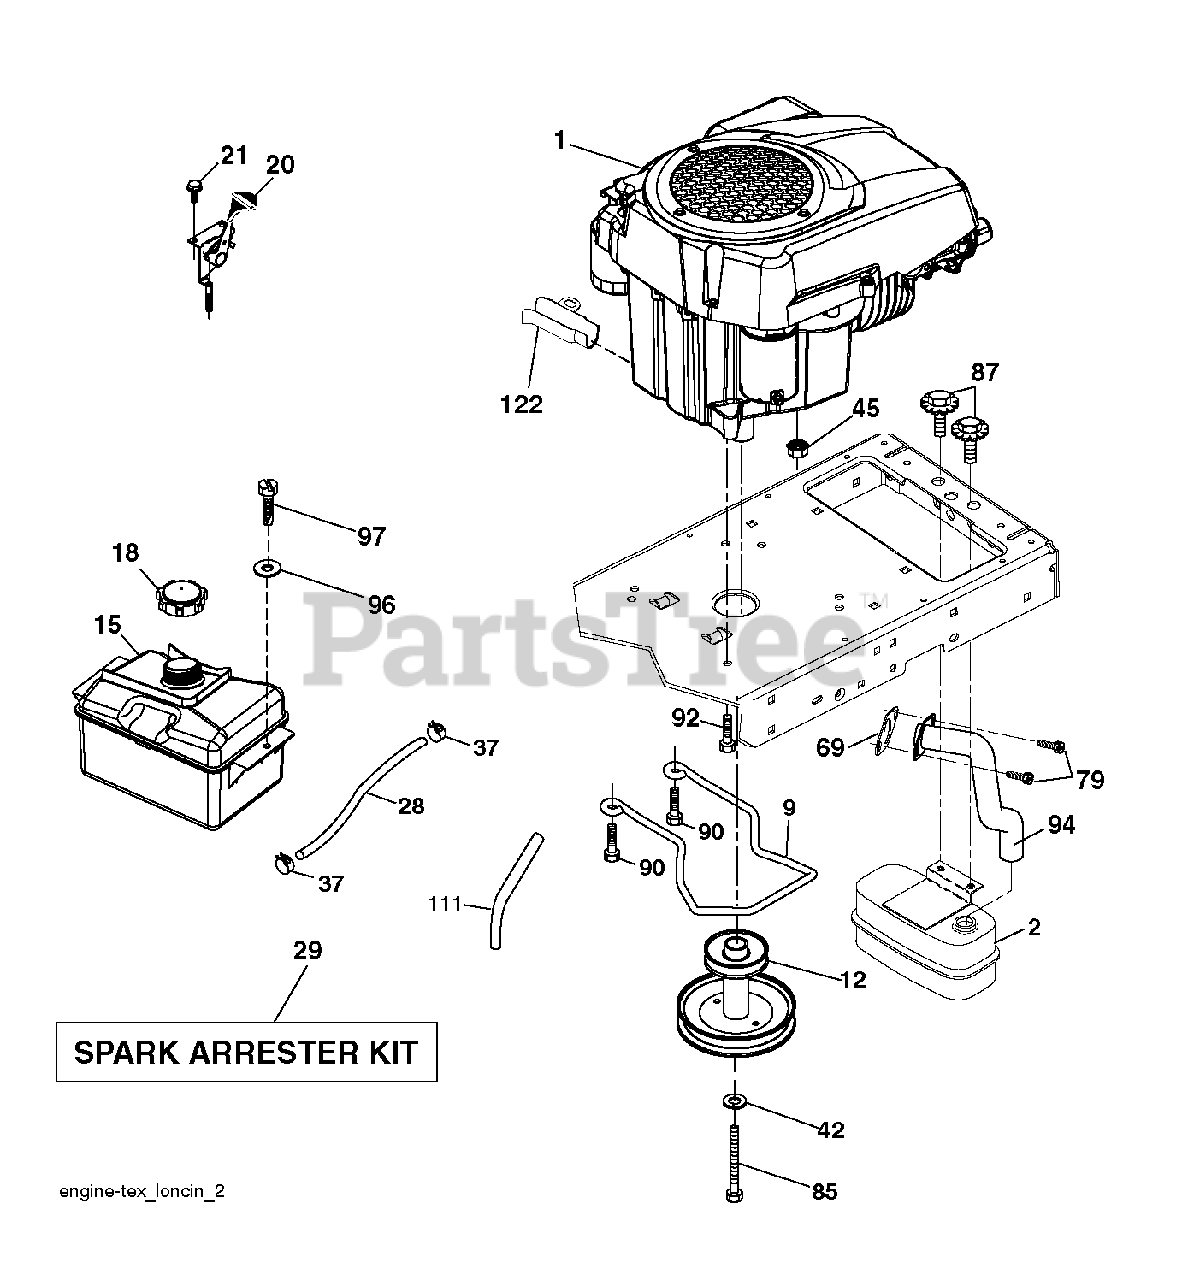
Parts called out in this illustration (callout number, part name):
2	Muffler Assembly, Single
9	KEEPER.BELT.ENG.4.25"2.BLT.431
12	ENGINE.PULLEY
15	TANK ASSY TANK ASSY. 1.5 GAL.
18	CAP.FUEL.2 WAY VENT
20	CONTROL.TH/CK.C.
21	SCREW.#10 X 0.750.BOS
28	LINE.FUEL.20"FRONT.EMI
29	KIT.SPARK ARRESTOR 794945 B&S
37	HOSE CLAMP
42	WASHER 7/16 LOCK
45	NUT
69	GASKET GASKET.EXHAUST.LONCIN 3
79	SCREW.SOCKET.HEAD.5/16-18
85	BOLT.HEX.7/16-20X4.GR5.1.5BLUE
87	BOLT, 5/16-18 X 1 3/4
90	SCREW 3/8-16X1
92	SCREW 3/8-16X1
94	TUBE TUBE.EXHAUST.LONCIN 452.T
97	SCREW HEXWSHR 1/4-20X3/4
111	RP PURGE LINE
122	EXTENSION DRAIN OIL
